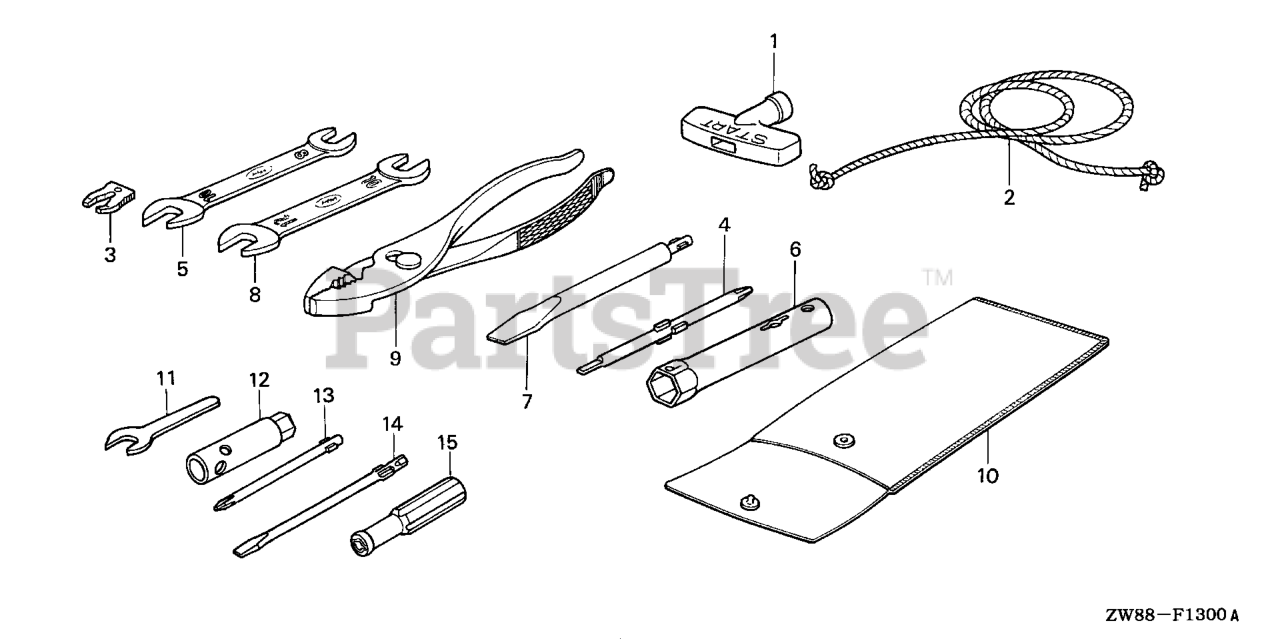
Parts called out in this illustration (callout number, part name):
1	GRIP, STARTER
2	ROPE, RECOIL STARTER (1300MM)
3	CLIP, EMERGENCY LOCK
6	WRENCH, SPARK PLUG
7	SCREWDRIVER, CHECK BOLT
8	WRENCH (10X12) (OPEN END)
9	PLIERS (135) (KOWA)
10	BAG, TOOL (160MM)
11	WRENCH (8MM) (OPEN END) (NOT AVAILABLE)
12	WRENCH, BOX (10MM) (NOT AVAILABLE)
13	SCREWDRIVER 1, PHILLIPS (NO.2)
14	SCREWDRIVER 3, STRAIGHT SLOT (NO. 2)
15	GRIP, SCREW DRIVER
